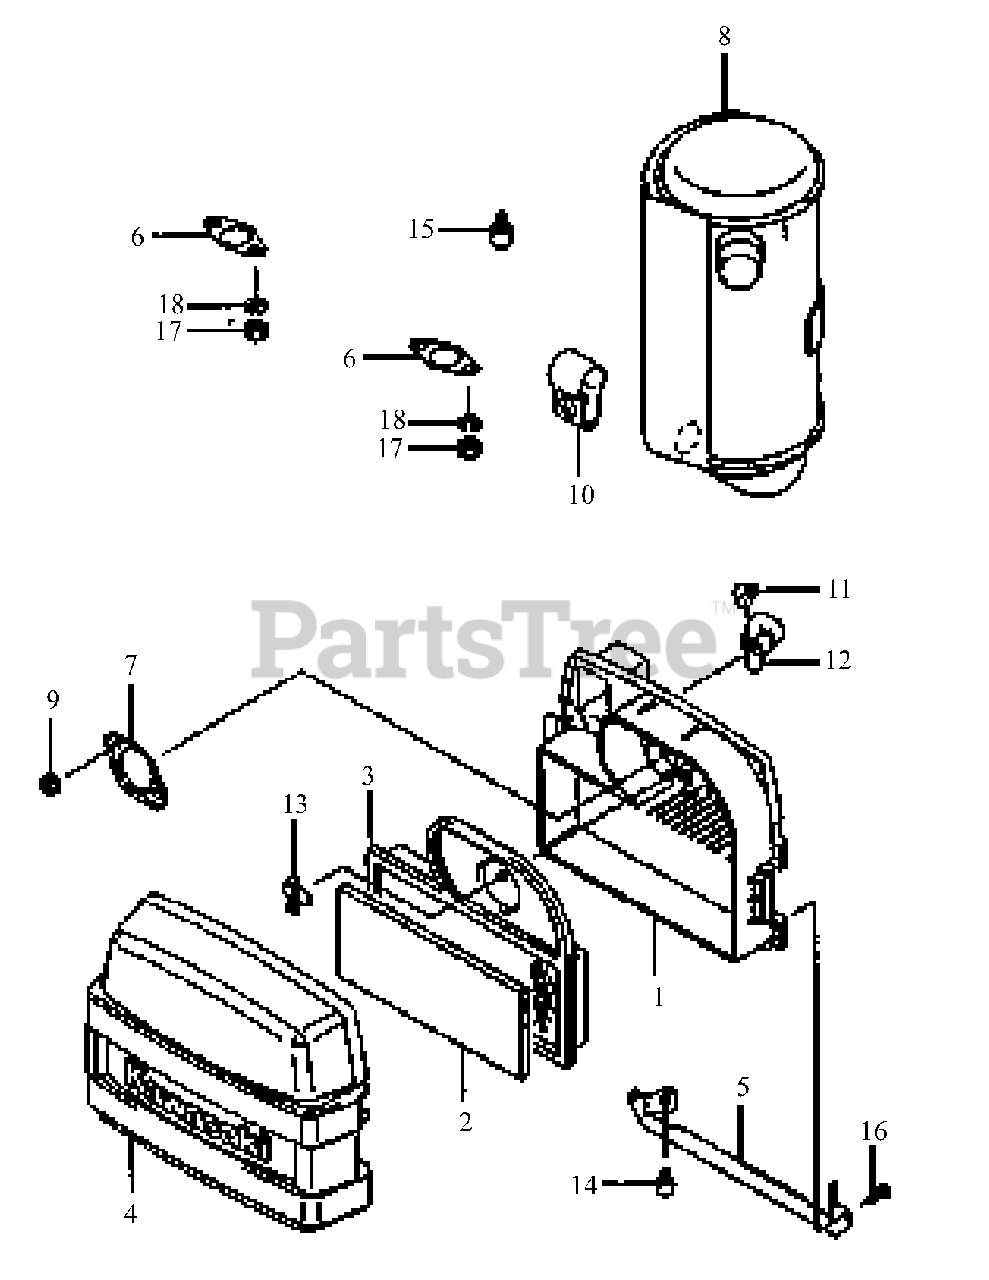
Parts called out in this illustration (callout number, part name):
1	Case, Air Filter
2	Element, Pre Filter
3	Element, Air Filter
4	Case, Air Filter
6	Gasket, Muffler
14	Bolt, Flange
15	Bolt, Flange
16	Screw
18	Washer, Spring
